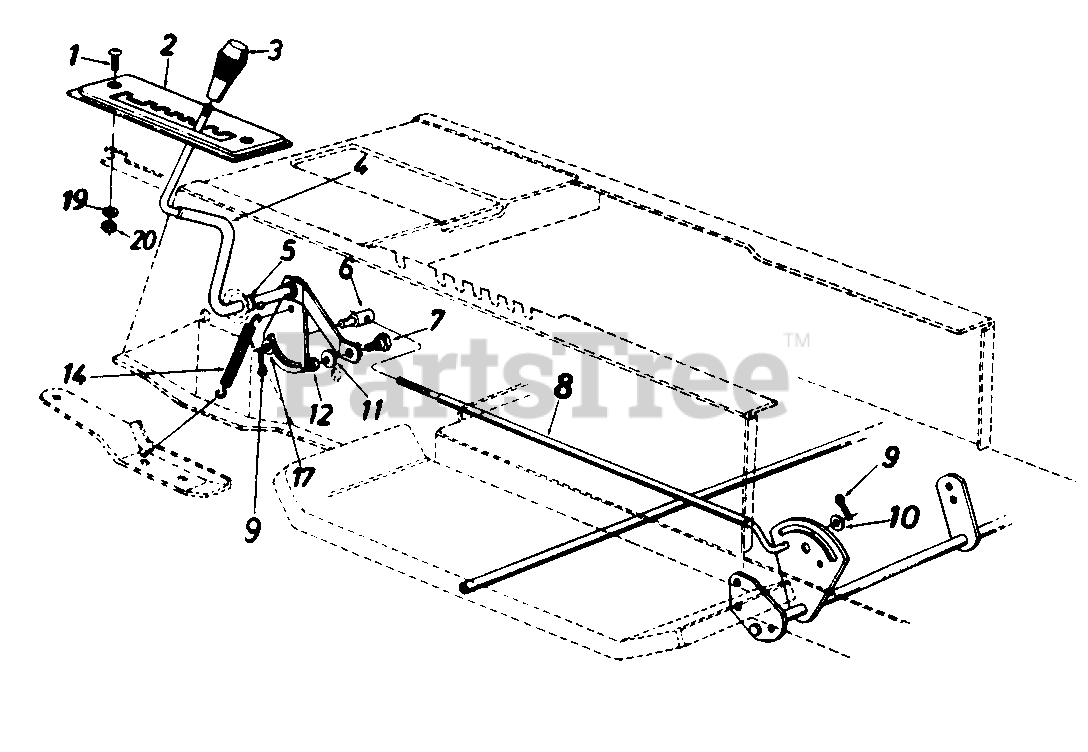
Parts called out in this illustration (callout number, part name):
1	Truss Mach. Scr. 1/4-20 x .75" Lg.
4	Speed Selector Lever Ass'y.
5	Flat Washer .53" I.D. x .93"
6	Ferrule 3/8-24 x .37" Dia.
7	Shoulder Bolt
8	Speed Control Link
9	Cotter Pin 3/32" Dia. x 1.0"
10	Fl-Wash .469" I.D. x .88"
11	L-Wash. 5/16" I.D.
12	Hex Nut 5/16-18 Thd.
14	Spring .38" O.D. x 3.18" Lg.
17	Fl-Wash .385" I.D. x .62"
19	L-Wash. 1/4" I.D.
20	Hex Nut 1/4-20 Thd.
